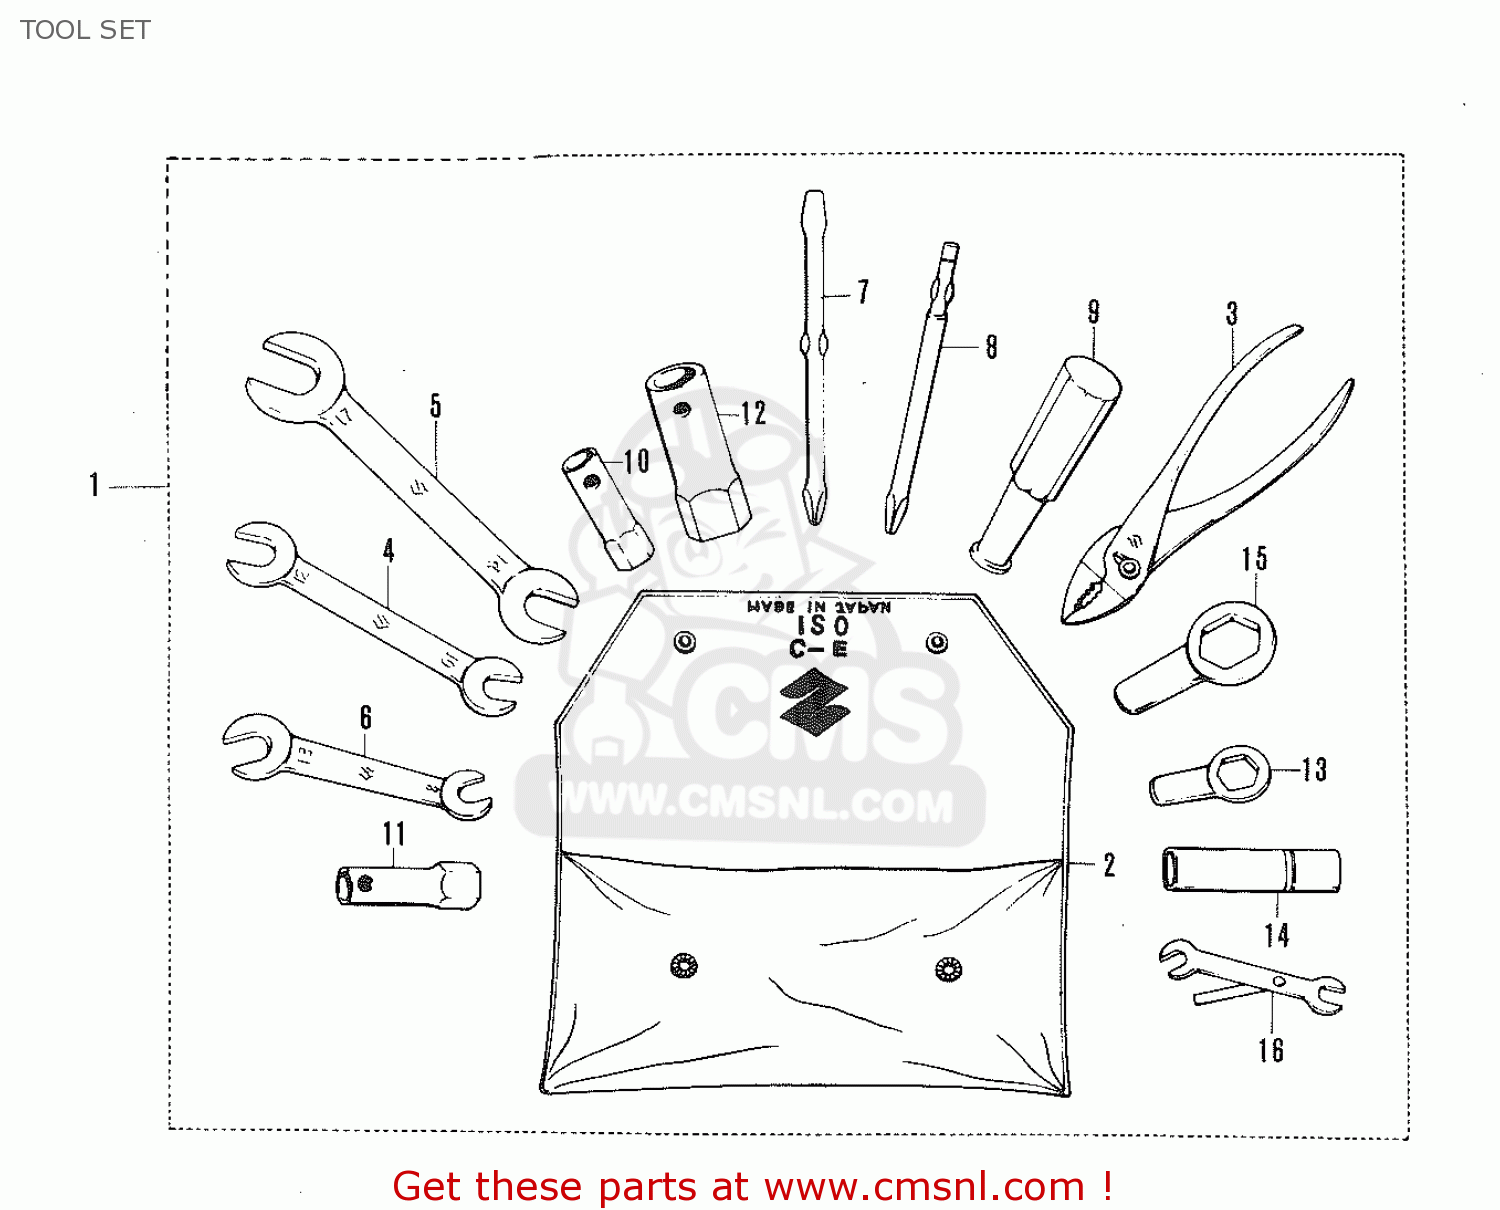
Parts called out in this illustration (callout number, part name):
1	TOOL SET
2	TOOL BAG
3	COMBINATION PLIERS
4	10X12MM OPEN END WRENCH
5	14X17MM OPEN END WRENCH
6	8X13MM OPEN END WRENCH
7	COMBINATION SCREW DRIVER
8	CROSS SCREW DRIVER
9	GRIP, SCREW DRIVER R,J,K,L,M
10	10MM BOX WRENCH
11	14MM BOX WRENCH
12	21MM BOX WRENCH
13	19MM OFFSET WRENCH
14	WRENCH HANDLE
15	22MM OFFSET WRENCH
16	WRENCH, CONTACT POINT
